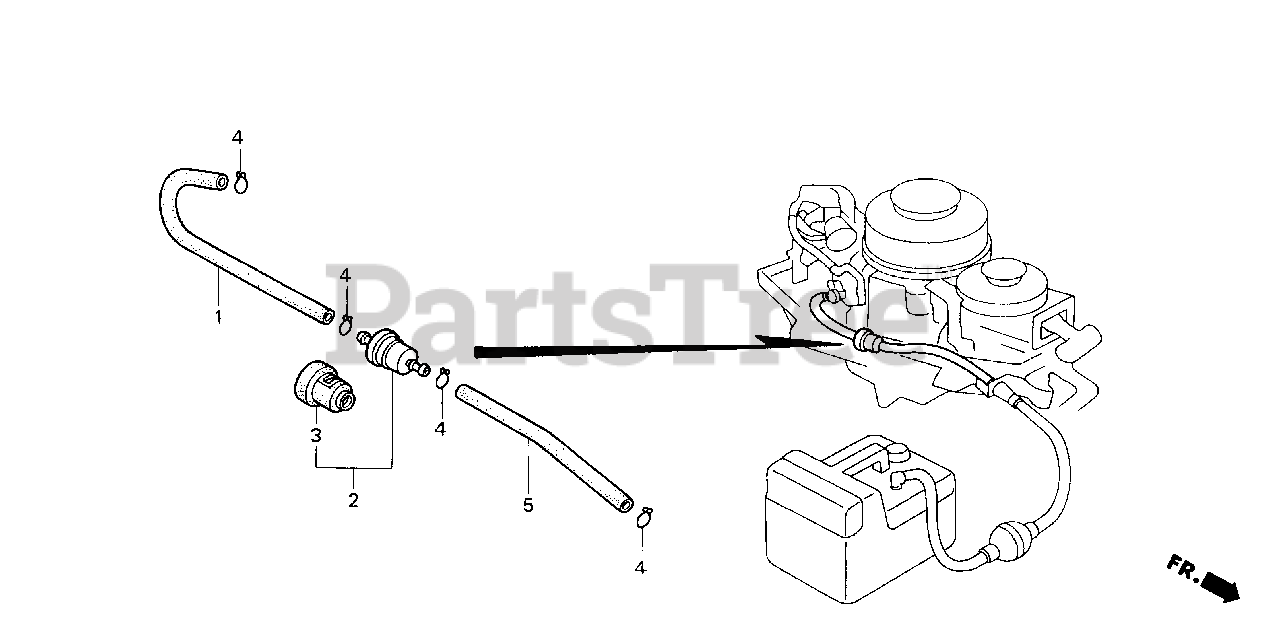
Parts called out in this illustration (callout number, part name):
1	TUBE, FUEL (4.5MM)
2	FILTER, FUEL
3	SUSPENSION, STRAINER
4	CLIP, TUBE (B8)
5	BULK HOSE, FUEL (4.5X3000) (4.5X265)
